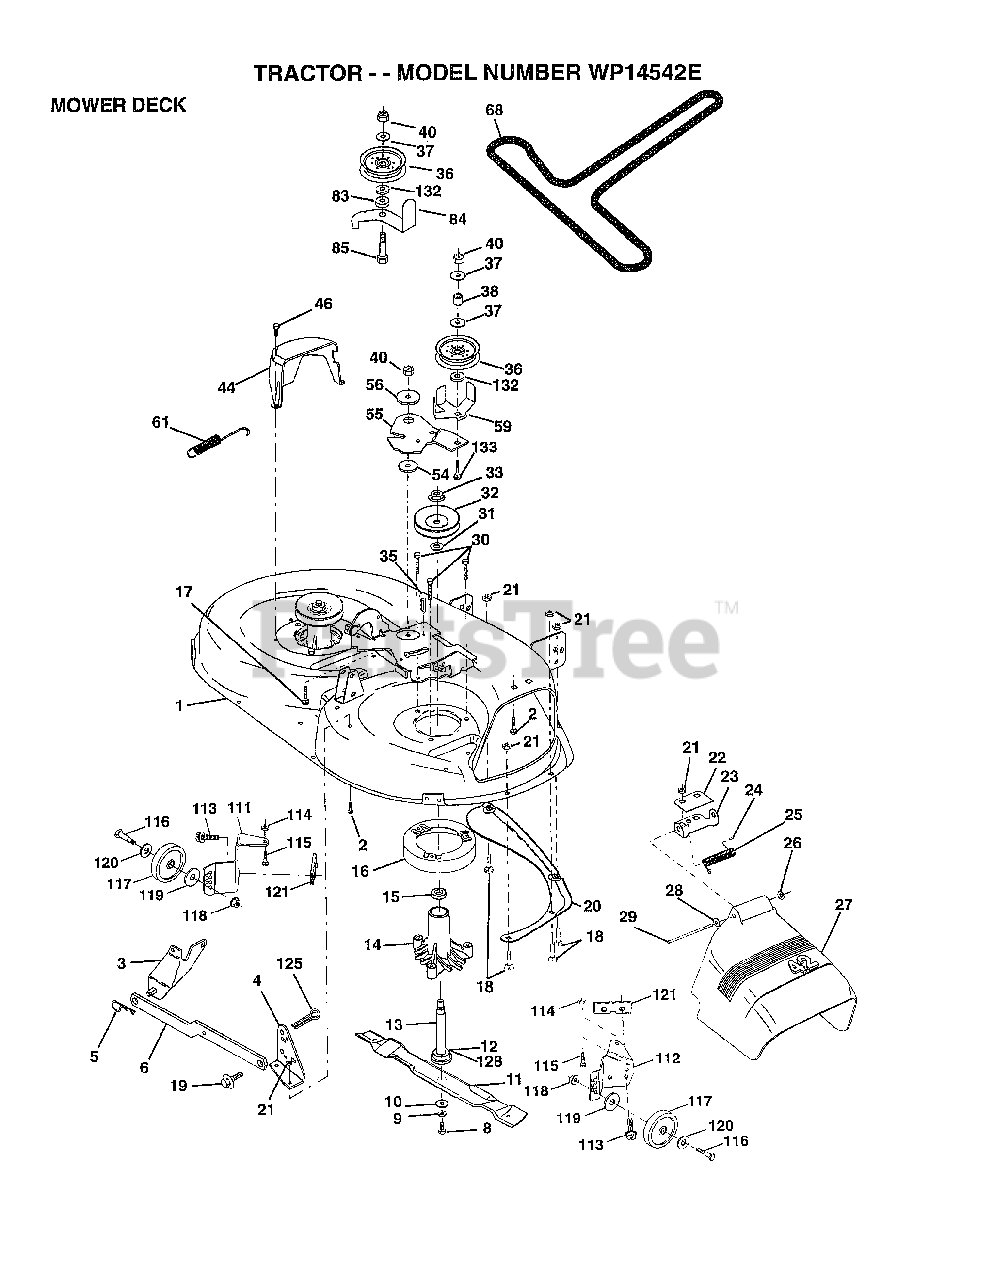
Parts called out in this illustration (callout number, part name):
1	DECK.WELD.42.
2	BOLT
3	BRKT ASM SWAY BAR
4	BRKT DECK SW BAR
8	BLADE BOLT
10	WASHER.HARD.BLADE
11	"BLADE.42"" HIPERF"
12	BEARING.BALL
14	HSG ASM MANDREL
15	BEARING
16	STRIPPER RND MWR
17	BOLT CARRIAGE
18	BOLT
19	BOLT SHD 5/16-18
20	BAFFLE VORTEX 42
22	STIFFENER BRKT
23	DEFLECTOR BRKT
25	SPRING TORSION
27	DEFLECTOR.SHIELD
28	WASHER
29	HINGE ROD
30	"SCREW-THD ROLL,WA"
31	WASHER
32	PULLEY.MANDREL.42
35	XMAS TREE FASTNER
36	FLAT IDLER PULLEY
37	WASHER
44	GUARD MAND LH BLK
46	SCREW.1/4-20X5/8
54	HARDENED WASHER
56	SPACER RETAINER
59	GUARD IDLER TUV
61	SPRING.EXTENSION
68	BELT.V.T-PATH
83	WASHER
84	"KEEPER-BELT,FIXED"
85	BOLT RDHD 3/8-16
111	BRACKET.GWHL.LH.
112	BRACKET.GWHL.RH.
113	SCREW
116	BOLT M
117	WHEEL.GAGE.BLK.PL
118	LOCKNUT
119	WASHER
120	WASHER
121	BRACKET.EXTRD.GWL
128	WASHER.FELT.
132	WASHER GT
133	BOLT
